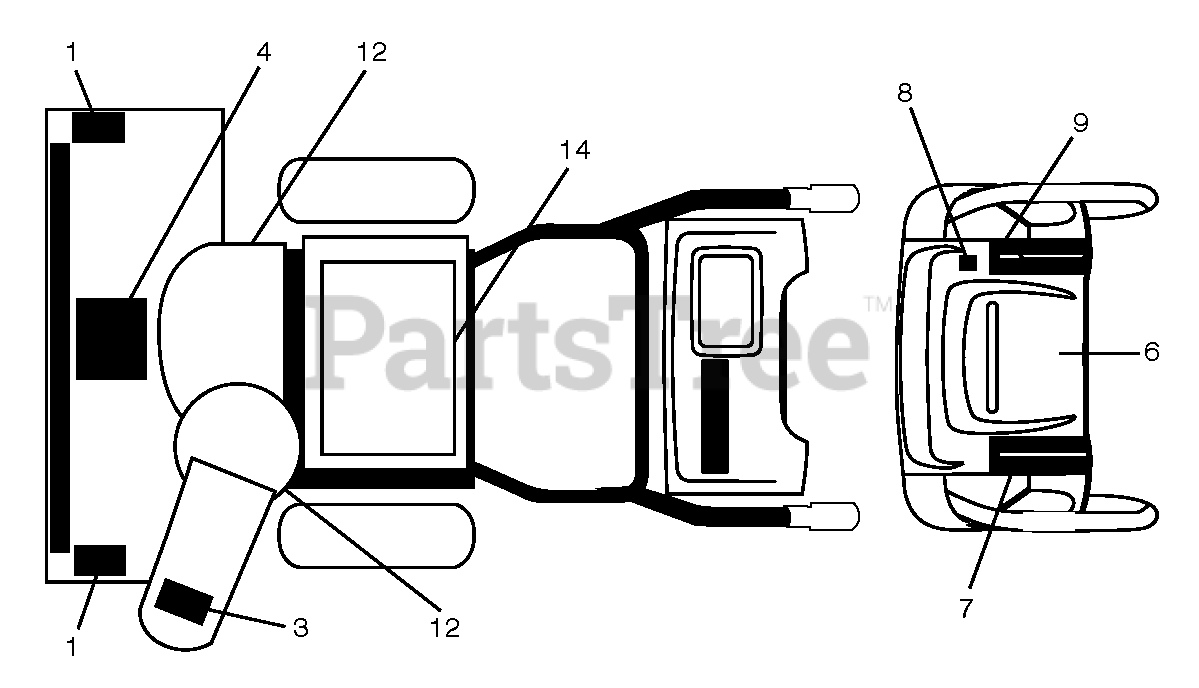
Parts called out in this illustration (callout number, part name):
1	DECAL.AUGER.SAFETY.
3	DECAL.CHUTE.SAFETY.
4	DECAL.AUGER."
7	DECAL CONSOLE DECAL DECAL.SNOW
8	DECAL.CONSOLE.HAND.WARMER
9	DECAL CONSOLE DECAL DECAL.SNOW
12	DECAL.BELT.GUARD.
14	DECAL.FENDER
